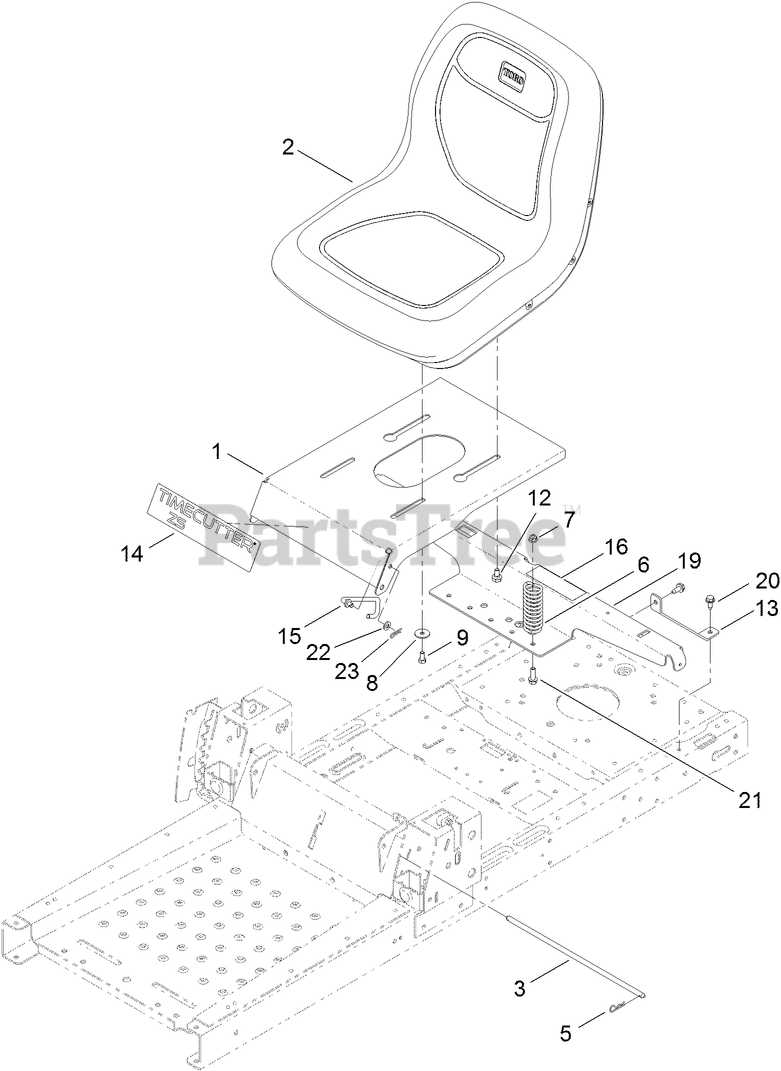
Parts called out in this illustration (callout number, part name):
2	SEAT-18 INCH
3	ROD-PIVOT, NARROW
5	PIN-COTTER
6	SPRING-COMPRESSION
7	NUT-HF, NI
8	WASHER-PIVOT
9	SCREW-HH
12	BOLT-SHOULDER,HFH
13	SUPPORT-TANK, REAR
14	DECAL-TIMECUTTER
15	STOP-SEAT
16	DECAL-SERVICE, CE
19	SUPPORT-POD
20	SCREW-HWHTF
21	SCREW-HHF
22	WASHER-PLAIN
